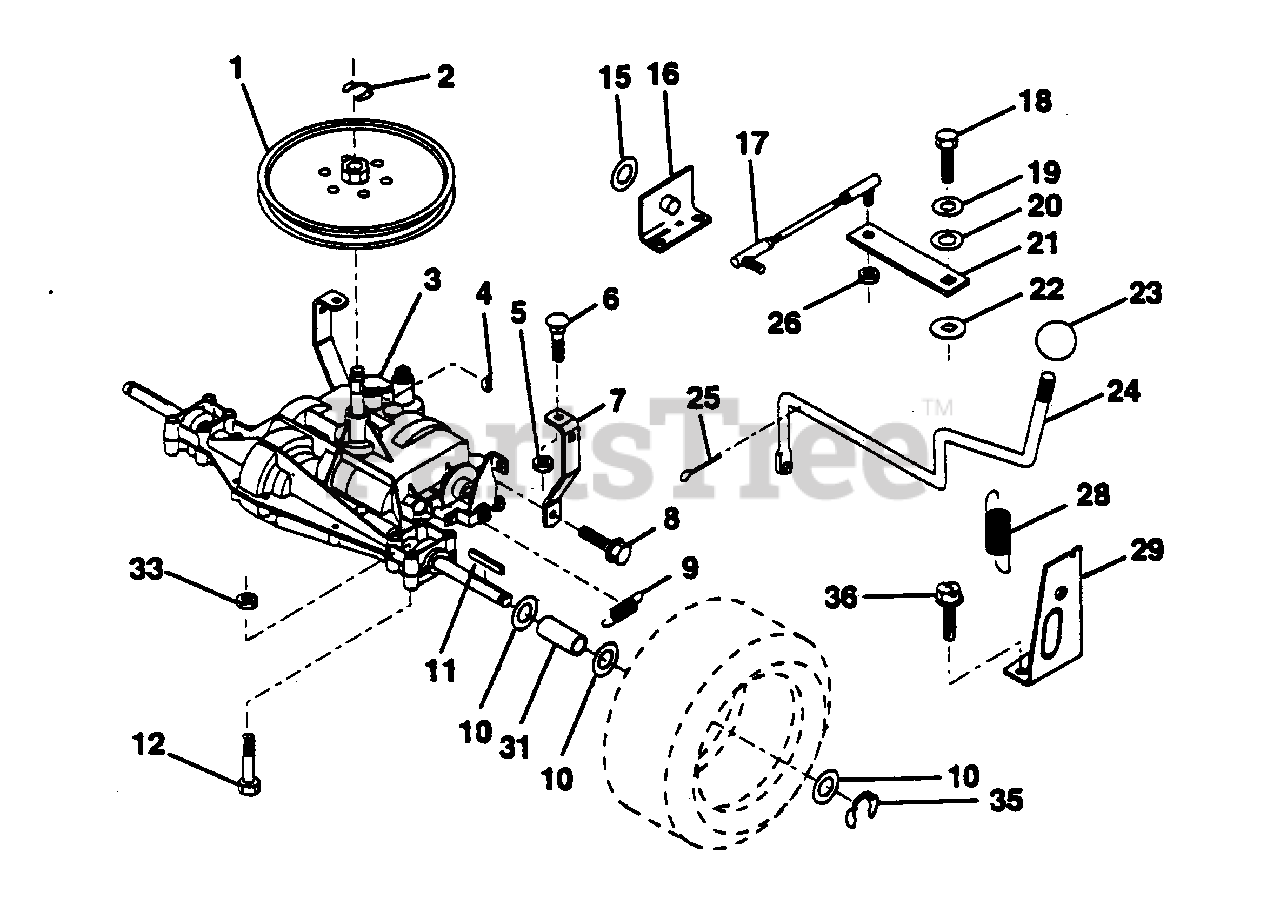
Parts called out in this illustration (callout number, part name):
2	Ring, Retainer
3	Transaxle, Dana 5 Spd. Model No. 4360-78
4	Key, Woodruff #9
5	Nut, Crownlock 5/16-18
6	Bolt, Carriage 5/16-18 UNC x 3/4
7	Strap, Torque
8	Screw 5/16-18 x 3/4
9	Spring, Brake
10	Washer 25/32 x 1-1/4 x 16 Ga.
12	Bolt, Fin Hex 3/8-16 UNC 2-3/4
15	Washer 17/32 x 1 x 16 Ga.
16	Support Handle Shift LH
18	Bolt, Fin Hex 1/4-28 UNF x 3/4 Gr. 8
19	Washer, Lock 1/4
20	Washer 9/32 x 3/4 x 10 Ga.
22	Washer, Shift Plate
23	Knob, Rd 1/2-13
25	Pin, Cotter 1/8 x 1
26	Locknut 5/16-24 UNF
28	Extension, Spring
29	Support Handle Shift RH
33	Nut, Crownlock 3/8-16
36	Screw, Thd. Cut. 1/4-20 x 1/2
